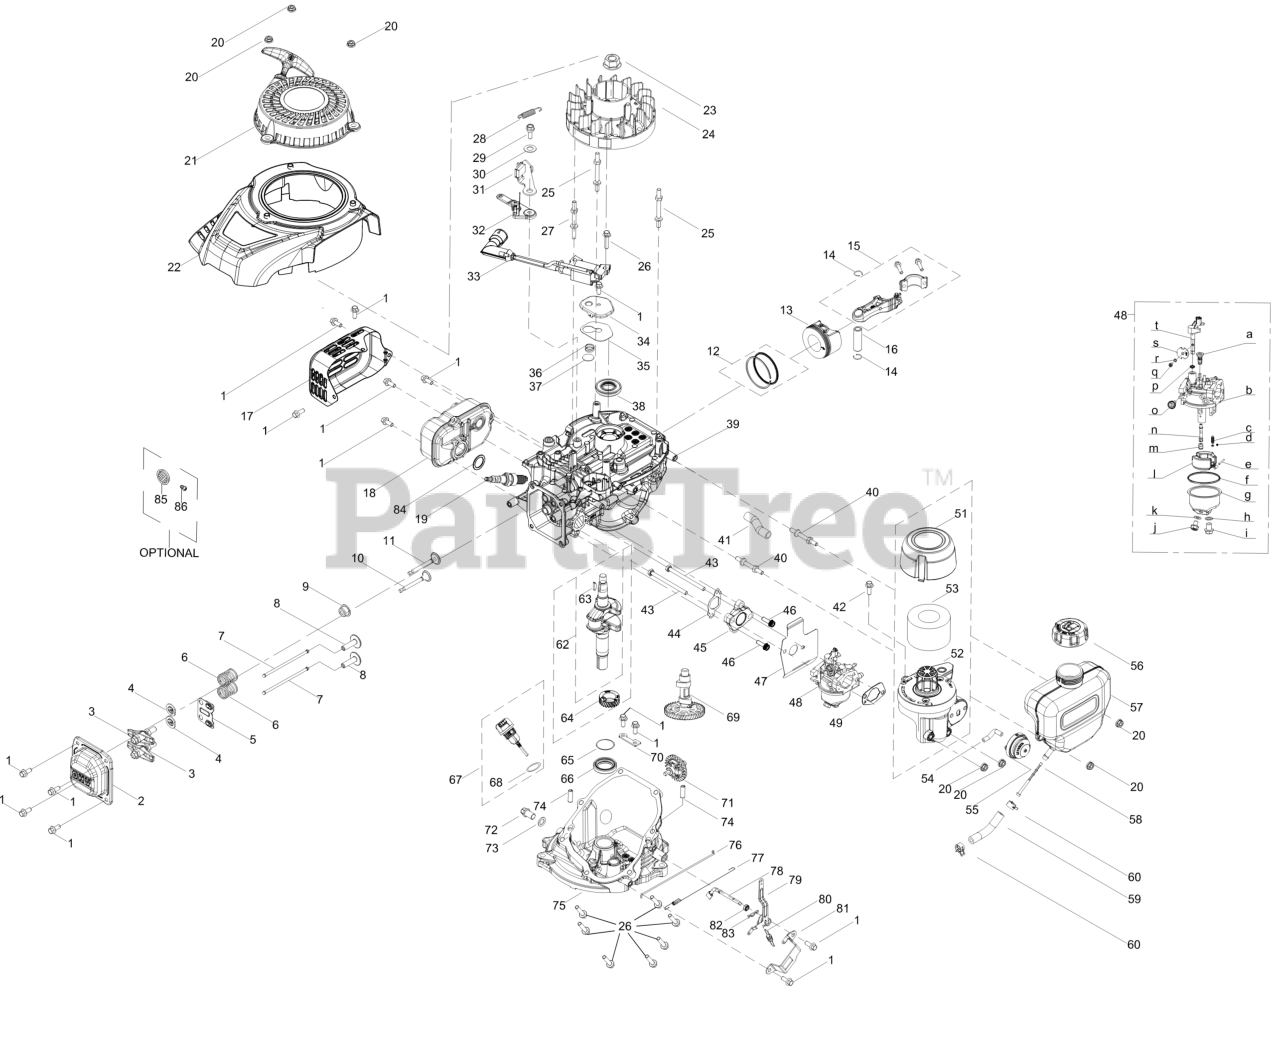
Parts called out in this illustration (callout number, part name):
1	BOLT M6-1 x 14 GR8.8
2	VALVE COVER
4	VALVE RETURN SPRING
5	PUSH ROD GUIDE
6	VALVE SPRING
9	INTAKE VALVE SEAL
10	EXHAUST VALVE
11	INTAKE VALVE
12	PISTON RING SET
14	WRIST PIN CLIP
15	CONNECTING ROD
16	PISTON PIN
17	MUFFLER GUARD
18	MUFFLER
19	SPARK PLUG (F6RTC/RN11YC/BPR6ES)
21	STARTER RECOIL ASSEMBLY
22	ENGINE SHROUD
23	FLYWHEEL NUT M14-1.5
24	FLYWHEEL
25	STUD M6 x 75
26	BOLT M6-1 x 25 GR8.8
27	STUD M6 x 73
28	ENGINE BRAKE SPRING
29	ENGINE BRAKE PIN M6-1.0 MM
30	FLAT WASHER 10x20x1.0 MM
31	ENGINE BRAKE ARM
32	ENGINE BRAKE LOWER BRACKET
33	IGNITION COIL
34	BREATHER COVER PLATE
35	BREATHER GASKET
36	BREATHER VALVE SPRING
37	BREATHER VALVE
40	FUEL TANK MOUNTING STUD M6X59.5
41	BREATHER HOSE
42	BOLT M6 x 16
43	BOLT M6X80
44	CARBURETOR INSULATION GASKET
45	CARBURETOR INSULATOR
46	BOLT M6X20
47	CARBURETOR GASKET
48	CARBURETOR
49	AIR FILTER BASE GASKET
51	AIR FILTER COVER
52	AIR FILTER BASE
53	AIR FILTER - FOAM
54	PRIMER HOSE
55	VENTED PRIMER ASSEMBLY
56	FUEL CAP ASSEMBLY
57	FUEL TANK
58	FUEL FILTER
59	FUEL HOSE
60	CARBURETOR HOSE CLAMP
62	CRANKSHAFT
63	WOODRUFF KEY
65	THRUST WASHER
66	LOWER CRANKSHAFT SEAL
67	DIPSTICK ASSEMBLY
68	DIPSTICK SEAL
70	GOVERNOR GEAR MOUNTING PLATE
71	GEAR GOVERNOR
72	OIL DRAIN PLUG
73	FLAT WASHER
74	DOWEL PIN 7X20
75	CRANKCASE COVER
76	THROTTLE LINKAGE
77	THROTTLE LINKAGE SPRING
78	GOVERNOR ARM SHAFT
79	GOVERNOR ARM ASSEMBLY
80	GOVERNOR SPRING
81	COMPONENT BRACKET
82	GOVERNOR SEAL
84	MUFFLER GASKET
85	SPARK ARRESTOR
86	SCREW M3.5 x 9.5
